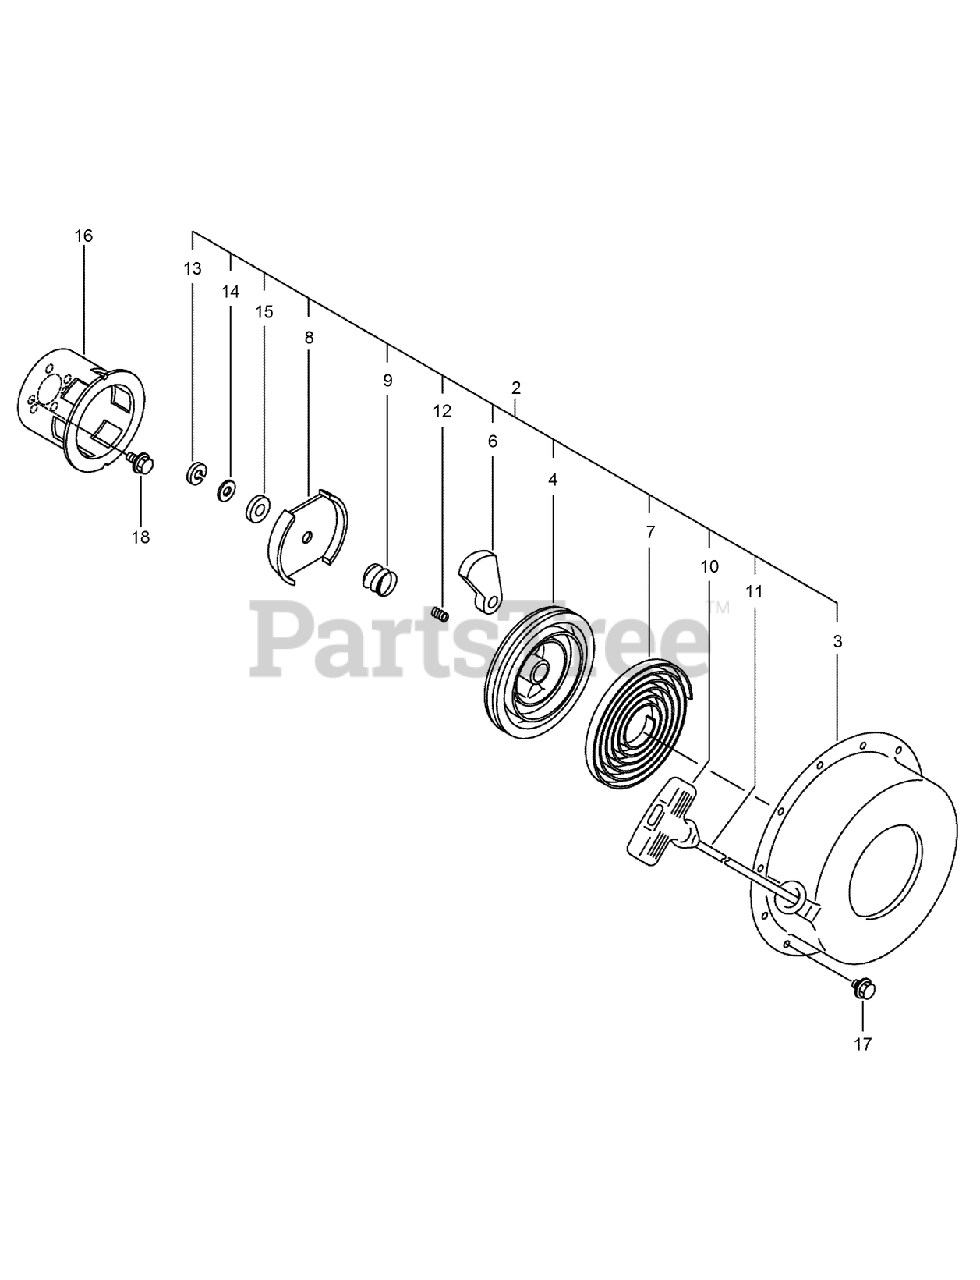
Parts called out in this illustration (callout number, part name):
2	RECOIL ASM
3	CASE-STARTER
4	REEL-RECOIL
6	RATCHET
7	SPRING-SPIRAL
8	GUIDE-RATCHET
9	SPRING-FRICTION
10	KNOB-STARTER
11	ROPE-STARTER
12	SPRING-RETURN
13	CIRCLIP
14	WASHER
15	WASHER
16	PULLEY-STARTER
